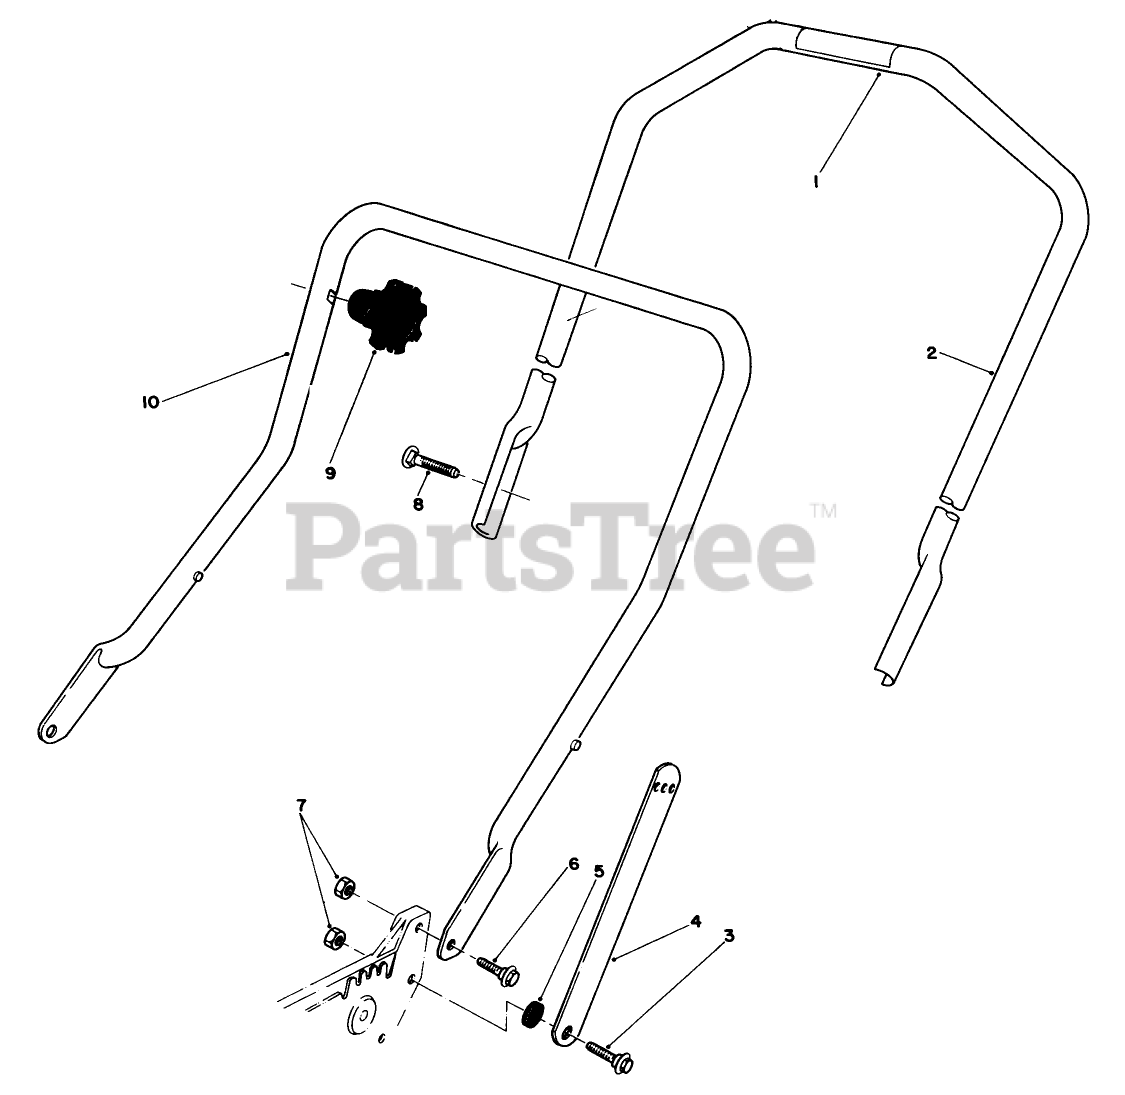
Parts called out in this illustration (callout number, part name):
3	SCREW-SHOULDER
5	SPACER
6	SCREW-SHOULDER
7	NUT-LOCK, NI
